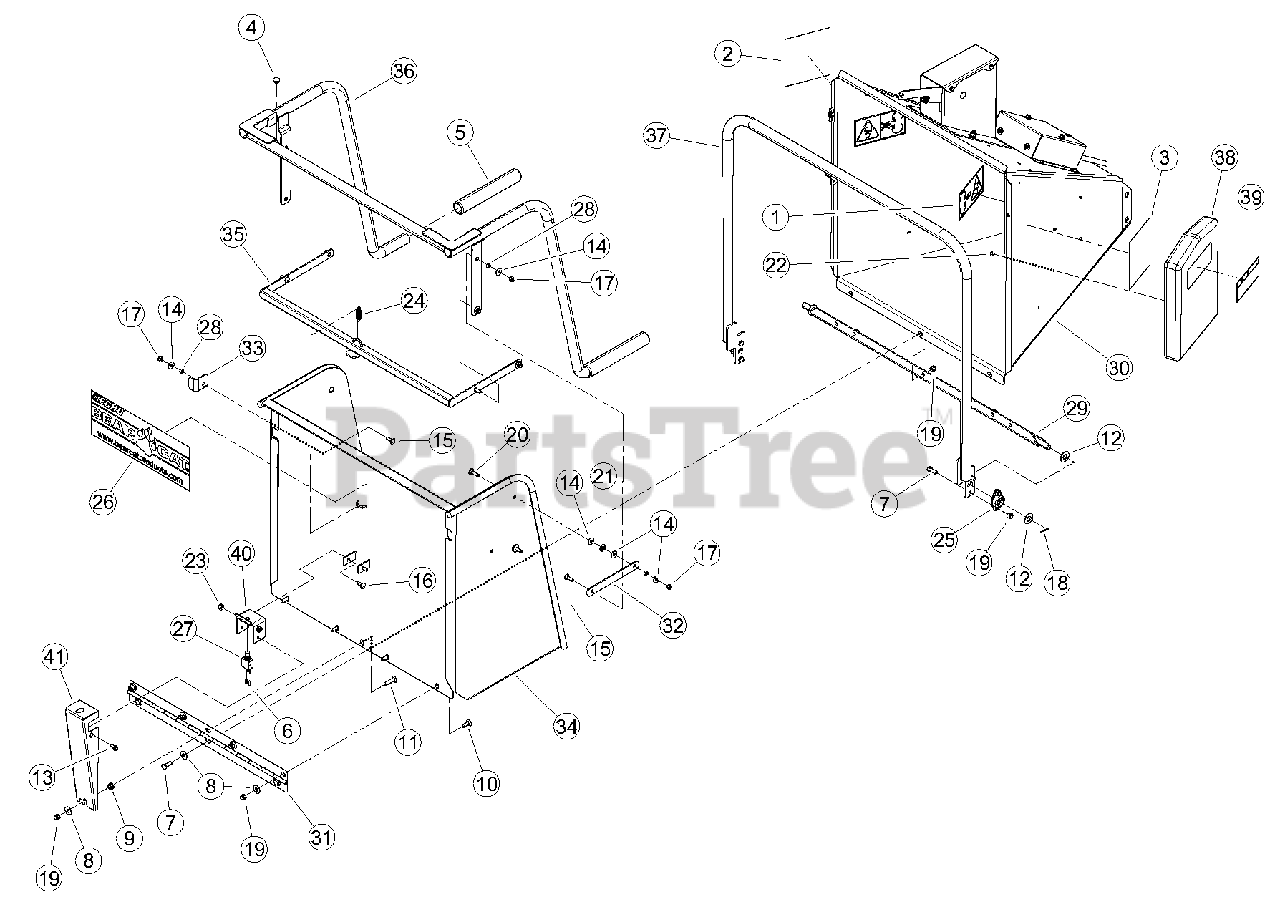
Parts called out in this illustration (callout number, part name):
1	DECAL, BLADE DANGER ISO
2	DECAL, FEED POSITION
3	DECAL, FEED POSITION
4	BUMPER, RUBBER
5	GRIP, 1.219 X 10.00
6	CONNECTOR, 1/4 QD MALE
7	BOLT, 3/8 X 1 HEX HD GR5 ZP
8	WASHER, 3/8 FLAT ZP
9	NUT, 3/8 SERR FLANGE NC ZP
10	BOLT, 3/8 X 1 CRG GR5 NC ZP
11	BOLT, 3/8 X 1-1/2 CRG GR5 NC ZP
12	WASHER, 5/8 SAE FLAT ZP
13	SCREW, 11/32 X 7/8 HWH AB THREAD ZP
14	WASHER, 5/16 FLAT ZP
15	BOLT, 5/16 X 1 CRG GR5 ZP
16	BOLT, 5/16 X 7/8 CRG GR5 NC ZP
17	NUT, 5/16 NE NYLOCK ZP
18	PIN, 1/8 X 1.00 ZP COTTER
19	NUT, 3/8 NE NYLOCK ZP
20	BOLT, 5/16 X 1-1/4" CRG GR5 ZP
21	WASHER, 5/16 ID - 7/8 OD NYLON FLAT
22	RIVET, AL BLIND 1/4 X 1/2 DOME HEAD
23	NUT, 5/16-18 NYLOCK-FLANGE
24	SPRING, 1/2 X 2.00 LG ZP
25	BEARING, 5/8 SIDE FLANGE MOUNT
26	DECAL, BEARCAT WEB
27	SWITCH, MOMENTARY IP67 NORMALLY ON (FOR SERVICE ORDER KIT 77536-00, CONTROL SWITCHES)
28	SPACER, IDLER PIVOT
29	WELDMENT, CONTROL PIVOT
30	WELDMENT, 4 IN. CHIPPER CHUTE
31	HINGE, EXTENSION TRAY
32	LINK, PARALLEL
33	LOCK, SAFETY BAR
34	WELDMENT, EXTENSION TRAY
35	WELDMENT, PIVOT TUBE
36	WELDMENT, SAFETY BAR
37	WELDMENT, CONTROL ARM
38	ASSEMBLY, MANUAL CONTAINER, SERVICE PART
39	DECAL, MUTILINGUAL MANUAL
40	BRACKET, SWITCH (FOR SERVICE ORDER KIT 77536-00, CONTROL SWITCHES)
41	SHIELD, SAFETYBAR SWITCH
